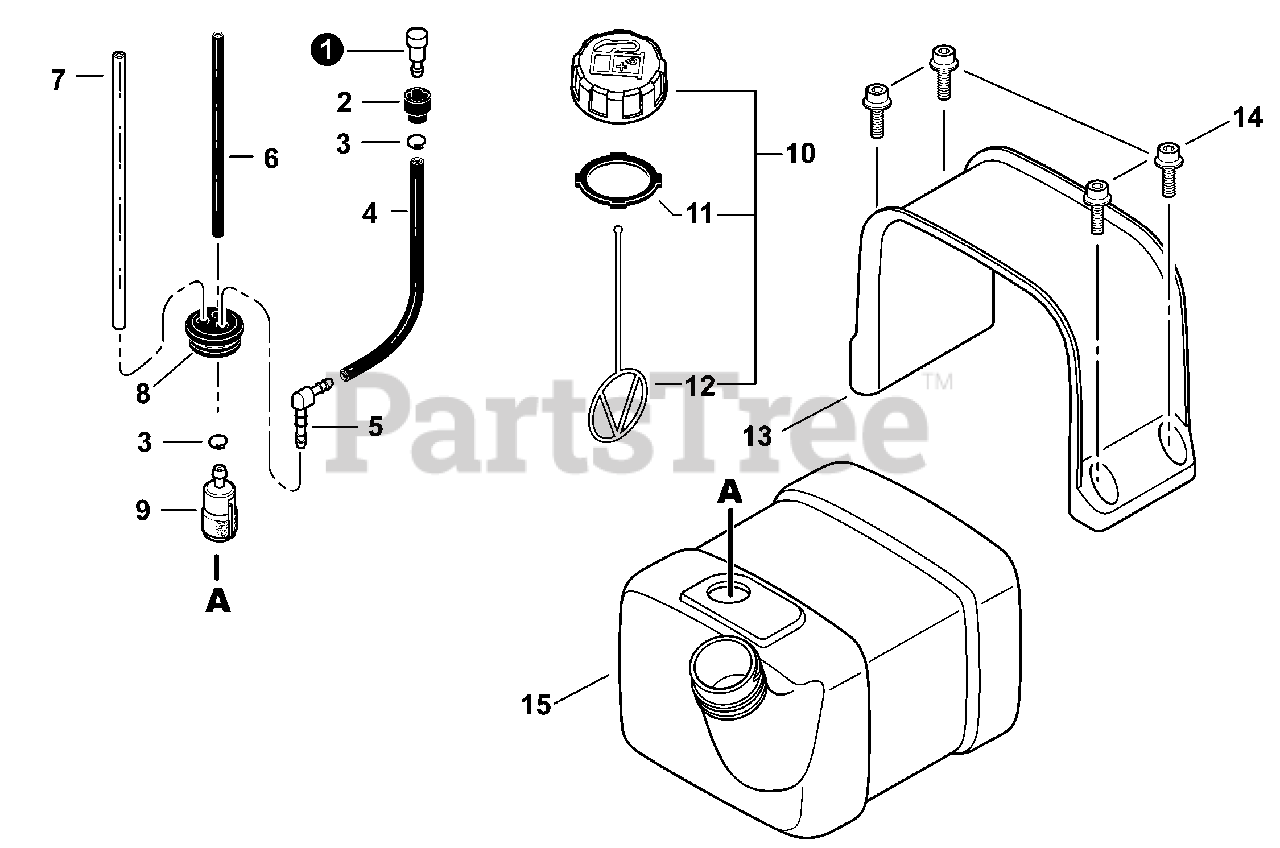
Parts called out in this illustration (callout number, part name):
1	VENT ASSY
2	HOLDER, VENT
3	CLIP 6.5MM
4	PIPE, VENT 3×6×145mm
5	CONNECTOR, PIPE 5.4
6	PIPE, FUEL 3×6×230
7	PIPE, FUEL RETURN 3×6×145
8	GROMMET, FUEL
9	FILTER, FUEL 125-528
10	CAP ASSY, FUEL
11	GASKET, FUEL CAP
12	CONNECTOR, CAP L= 100mm
13	BRACKET, FUEL TANK
14	BOLT 5×16
15	TANK, FUEL
